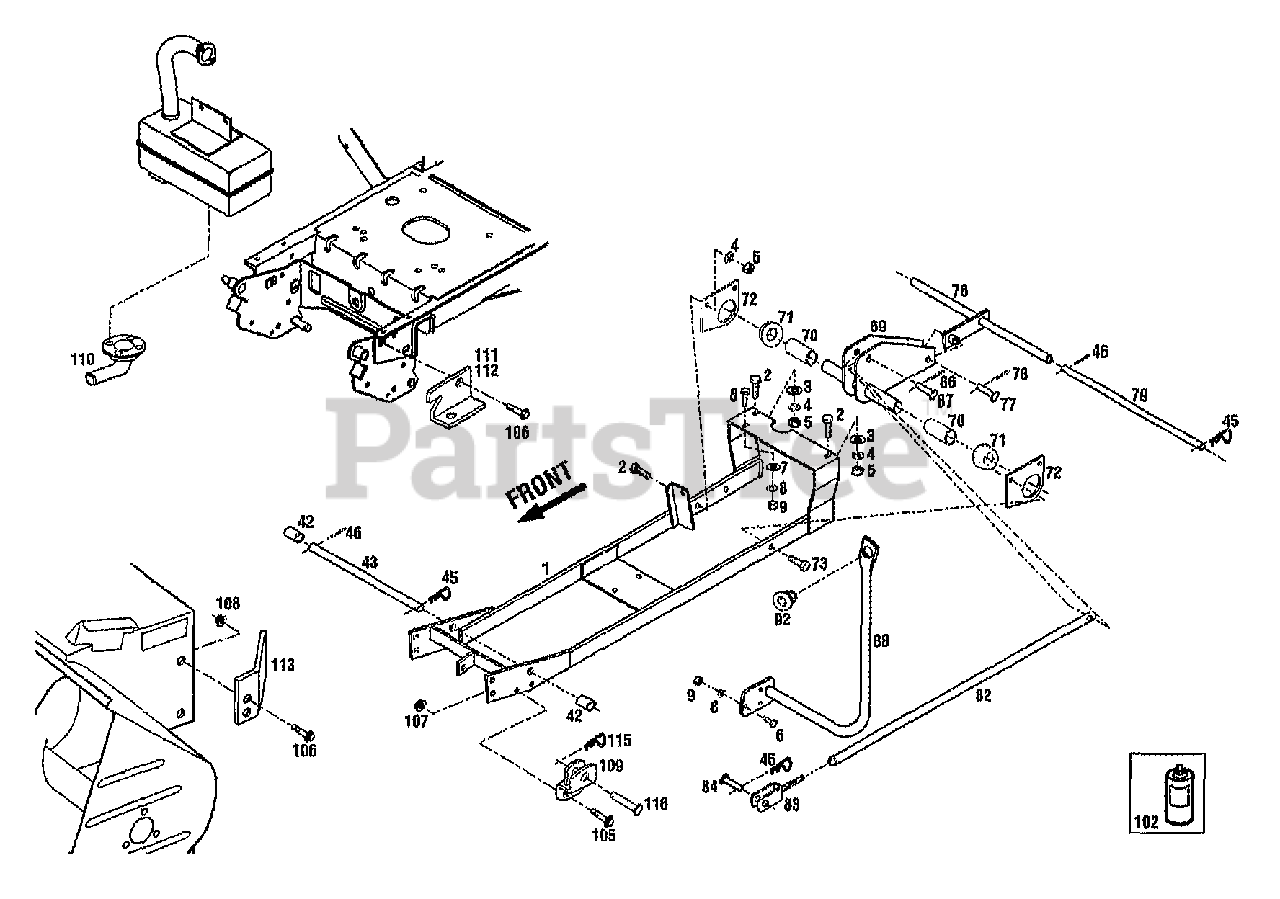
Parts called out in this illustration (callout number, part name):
1	SUBFRAME ASSY
2	SCR-HH 3/8-16X1.0 G5 ZP
3	WASHER-FLAT 3/8 SAE
4	WASHER-LK .375 @ DEPL
5	NUT-HEX 3/8-16 ZP
6	SCR-HH 5/16-18X1.0 G5 ZP
7	WASHER-FLAT 5/16 SAE
8	WASHER-LK .312 ZP
9	NUT-HEX 5/16-18 ZP
42	SPACER (14078)
43	ROD-SUPPORT (14078)
45	PIN-HITCH .125X2.56 ZP
46	PIN-ROLL
69	ROD-LIFT WELDMENT (14078)
70	TUBE-TORQUE (14078)
71	BEARING-1" (14078)
72	PLATE-END (14078)
76	ASSM-LIFT (14078)
77	PIN-CLEVIS .5X2.0 ZP
78	PIN-COTTER .120X1.00 ZP
79	ROD-LIFT (14078)
82	SHAFT-LIFT (14078)
83	CLEVIS
84	PIN-CLEVIS
86	PIN-COTTER .120X1.00 ZP
87	PIN-CLEVIS
88	HANDLE-SUPPORT
92	GROMMET
102	PAINT-BLACK SPRAY
105	SCR-HFLK 5/16-18X.75 ZP
107	NUT-HFLK 5/16-18 ZP
108	NUT-HFLK 3/8-16 ZP
109	ASSM-SUPT BRKT 1774015
110	PIPE-EXHAUST
111	BRKT-SPRING RH
112	BRKT-SPRING LH
113	SHIELD-EXHAUST
115	PIN-HITCH .125X2.56 ZP
116	PIN-CLEVIS
